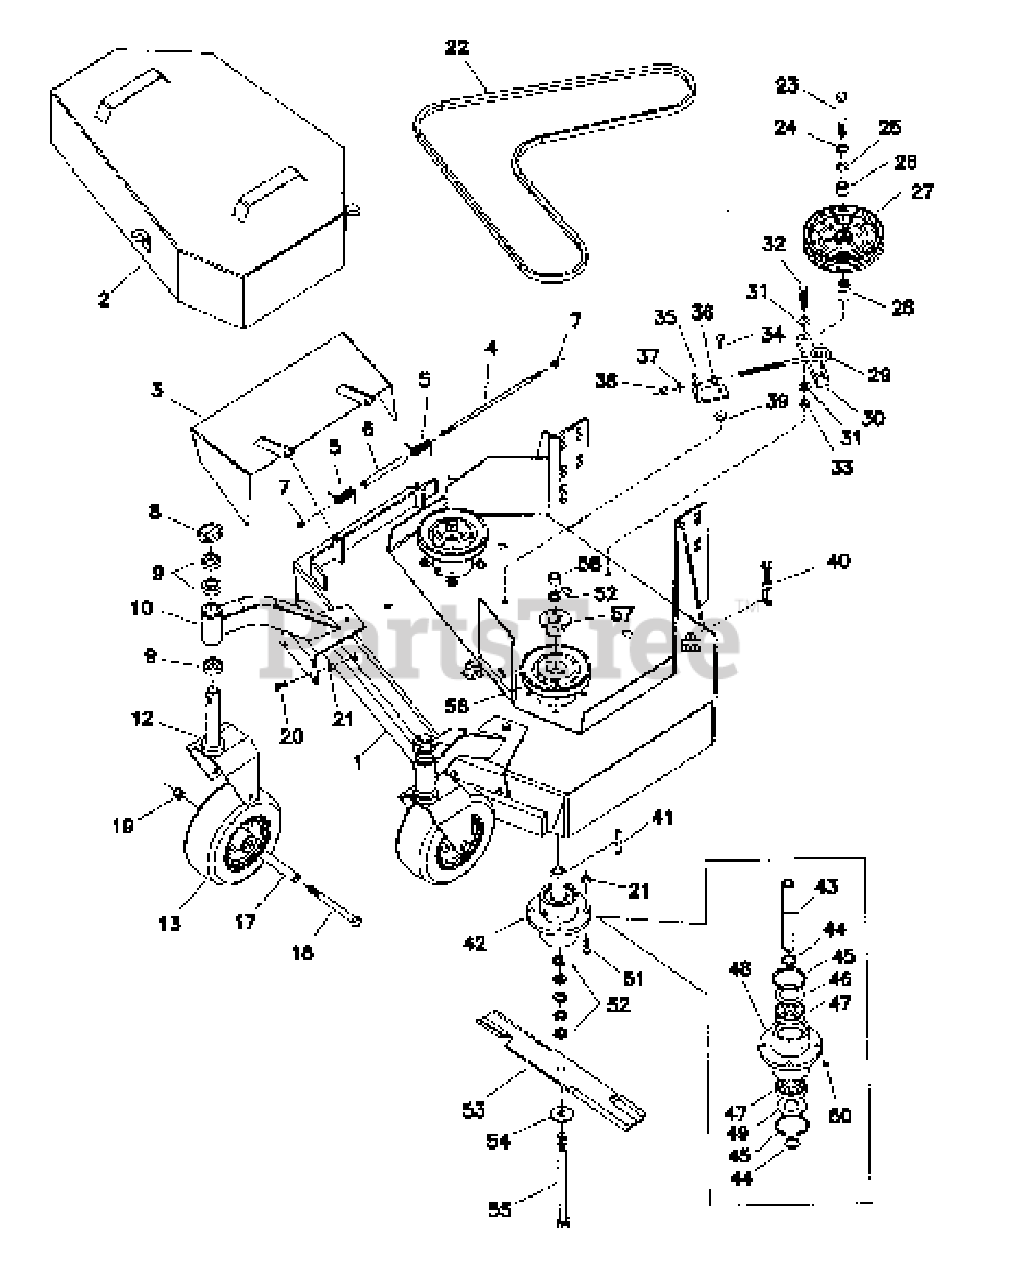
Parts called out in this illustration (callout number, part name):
1	36" MOWER HOUSING
2	36" MOWER GUARD
3	DISCHARGE CHUTE
4	CHUTE PIVOT ROD
5	SPRING, Deflector Retaining
6	SPACER, Spring
7	NUT, Hex, Nylon Lock, 5/16-18
8	LYNCH PIN
9	SPACER, Caster
10	CASTER MOUNT ARM, Complete (Includes Ref 11 &50)
11	BUSHING, Flange
12	CASTER TIRE MOUNT
13	CASTER TIRE, Compete (Includes Ref 14, 15 & 16)
14	TIRE
16	HUB, w/BEARINGS
17	CASTER AXLE
18	CAPSCREW, Hex head, 1/2-13 x 5-1/2
19	NUT, Hex, Nylon Lock, 1/2-13
20	CAPSCREW, Hex Head, 5/16-18 x 3/4
21	NUT, Hex, Serrated Flange, 5/16-18
22	BELT
23	CAPSCREW, Hex Head, 1/2-20 x 3-1/2
24	WASHER, Lock, 1/2
25	WASHER, 1/2
26	SPACER, Idler, Short
27	*PULLEY, FLAT IDLER, 6-3/4"
28	SPACER, Idler, Long
29	EYEBOLT
30	IDLER ARM
31	WASHER, 7/16
32	CAPSCREW, Hex Head, 7/16-20 x 1-3/4
33	NUT, Hex, Nylon Lock, 7/16-20
34	CAPSCREW, Hex Head, 3/8-16 x 1
35	EYEBOLT ANCHOR
36	NUT, Hex, 5/16-18
37	WASHER, 3/8
38	NUT, Hex, Nylon Lock, 3/8-16
39	GUARD HOLD DOWN
40	KEY, 1/4 x 2-1/2
41	SPINDLE ASSEMBLY, Complete (Includes Ref 43-50)
42	SPINDLE SHAFT
43	SNAP RING
44	SNAP RING
45	WASHER, Top
46	BEARING
47	HOUSING
48	SPINDLE WASHER, Bottom
49	GREASE FITTING
50	CAPSCREW, Hex Head, 5/16-18 x 1-1/4
51	SPACER, Blade
52	BLADE
53	WASHER, 5/8
54	CAPSCREW, Hex Head, 5/8-11 x 9-1/2
55	PULLEY, Spindle
56	HUB
57	NUT, Hex, 5/8-11
